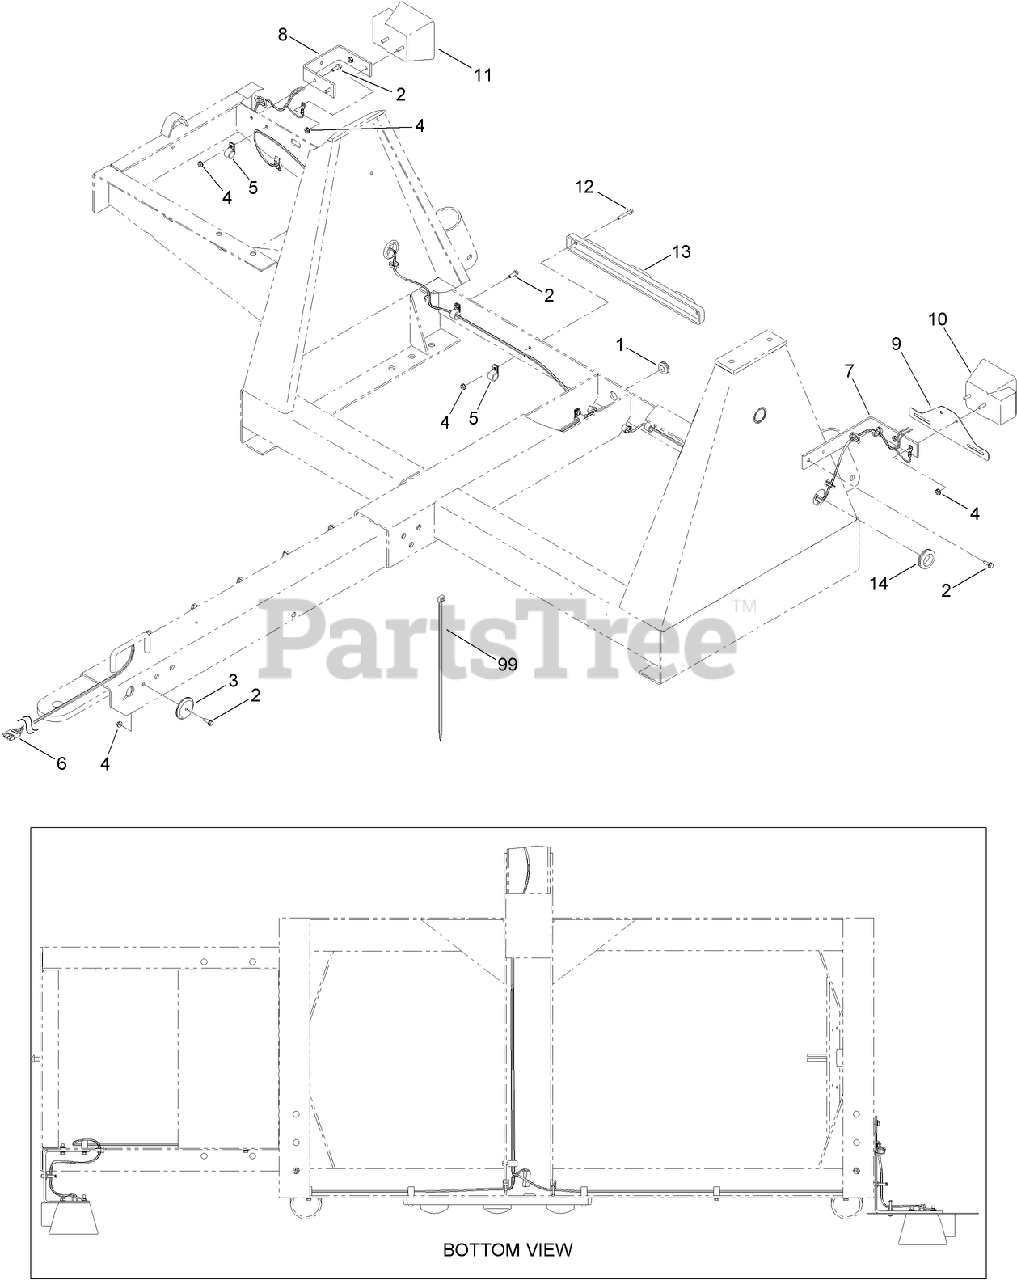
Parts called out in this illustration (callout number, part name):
1	GROMMET
2	SCREW-HHF
3	Reflector-Amber
4	NUT-KEPS
5	CLAMP-CABLE
6	HARNESS-WIRE, TRAILER LIGHTS
7	BRACKET-L
8	BRACKET-U
9	HOLDER-PLATE, LICENSE
10	LIGHT-TAIL, LH
11	LIGHT-TAIL, RH
12	SCREW-HHF
13	LIGHT-IDENTIFICATION, TRAILER
14	GROMMET
99	TIE-CABLE
